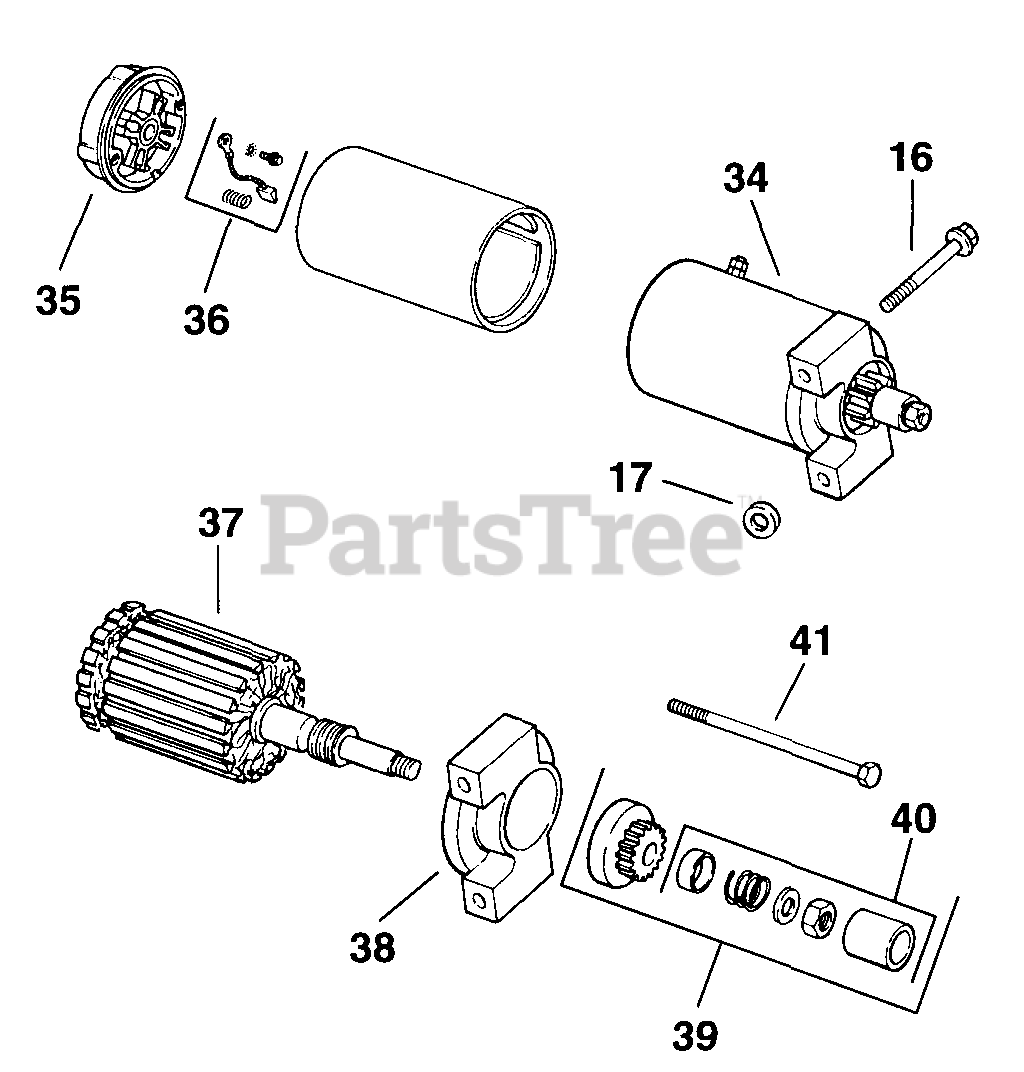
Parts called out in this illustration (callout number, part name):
17	WASHER, FLAT 11/32"
34	STARTER - USE 12 098 13
35	CAP - USE 12 227 11
36	KIT - USE 82 755 28
37	ARMATURE - DISCONTINUED
38	CAP - USE 12 227 05
39	DRIVE KIT - USE 12 755 53
40	DRIVE KIT - USE 12 755 53
41	SCREW - DISCONTINUED
